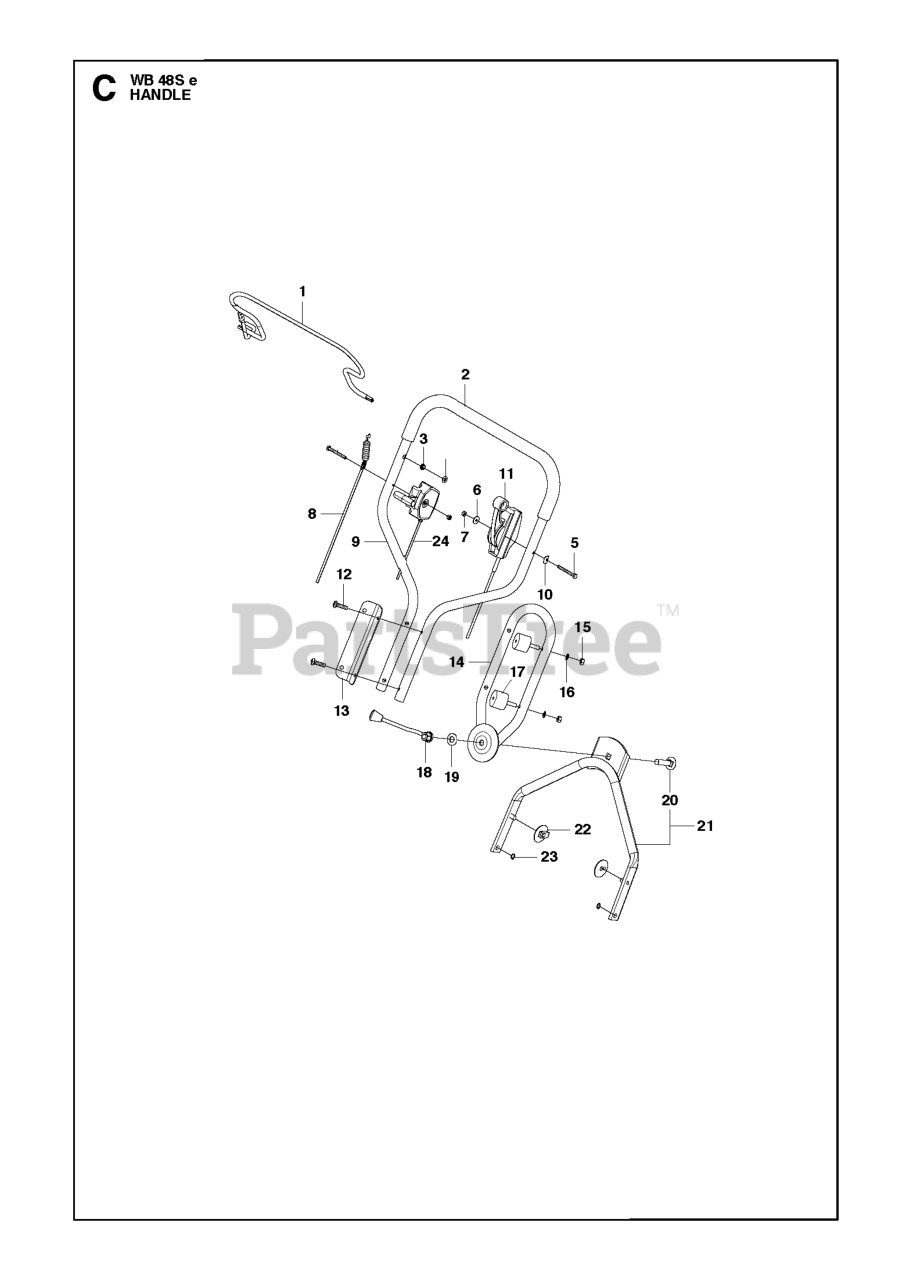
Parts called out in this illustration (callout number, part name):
5	SCREW M6X55
7	NUT FLANGE - M6
15	NUT
23	RETAINING RING SGA 10
